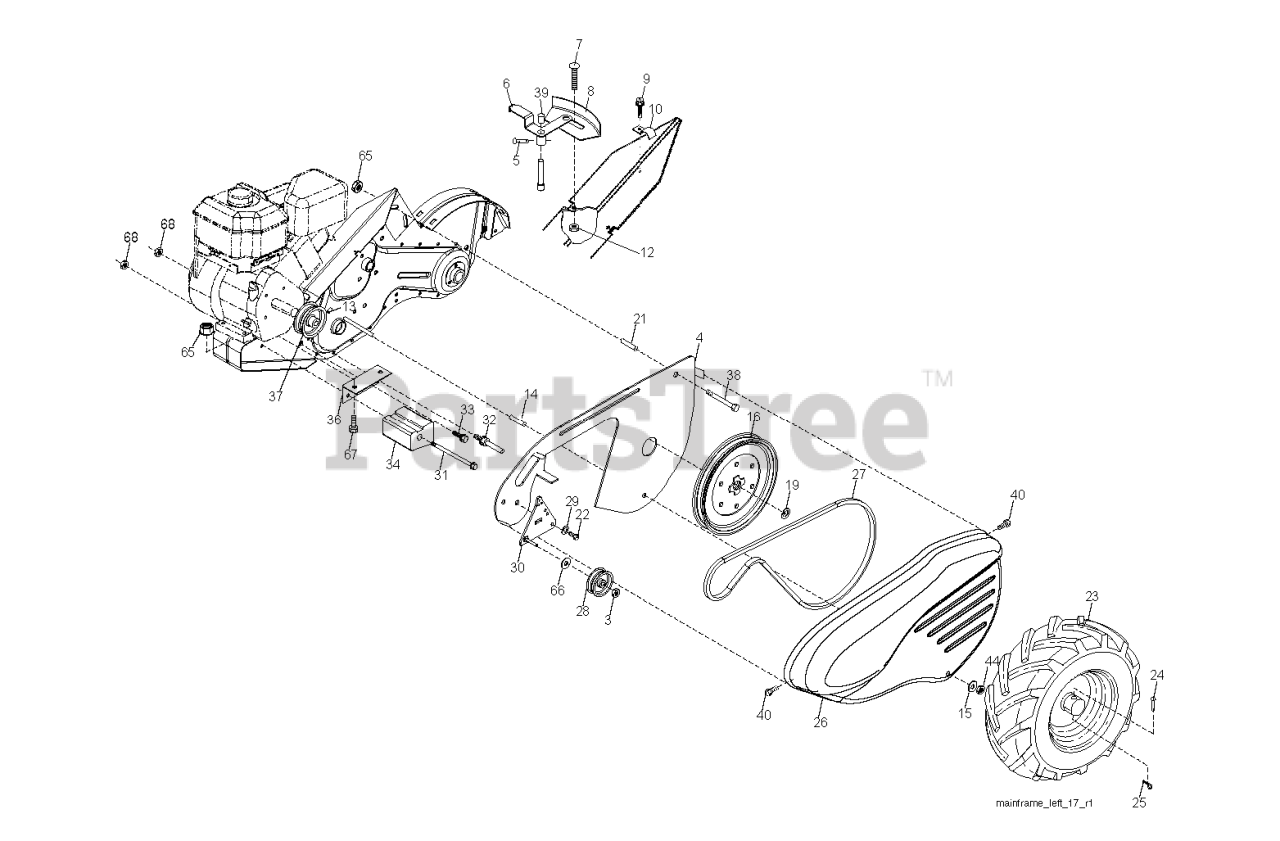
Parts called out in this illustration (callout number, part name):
3	NUT.HEX.3/8-16UNC
4	SHIELD
5	PIN.SPIROL.FLARED
6	LEVER.ASM.SHIFT.RED
8	RP.PANEL.SHIFT
9	TAPPING SCREW
10	CONDUIT.CLIP.PLATED
12	NUT
14	SPACER CRT
15	WASHER
16	SHEAVE, TRANSMISSION
19	RETAINING RING LT
21	SPACER-SPLIT.327 X .42
23	RIM.ASM.6".SILVER
23	TIRE.13X5-6.CHEVRON.TILLER
23	VALVE STEM LT
24	RIVET,DRILLED
25	RETAINER M
26	RP BELT GUARD
27	V-BELT
28	PULLEY-IDLER TI
30	BRACKET.ASM.IDLER.BLACK
31	BOLT.FIN.HEX.3/8-16UNC
32	SHIFT ARM CRT
33	BOLT
34	COUNTERWEIGHT.LH.CRT
36	BRACKET LH CRT
37	RP.ENGINE PULLEY
38	BOLT
39	CAP.PLUNGER.BLACK
40	SCREW.HEX.WSH.SLT.#10-24X.50
44	NUT.71038.31-18.HEX.NYLOCK
65	LOCKNUT-FLANGE 5/16-18
66	WASHER
67	BOLT, HEX 5/16-18X1-3/4
69	KEEPER.BELT.ENGINE
